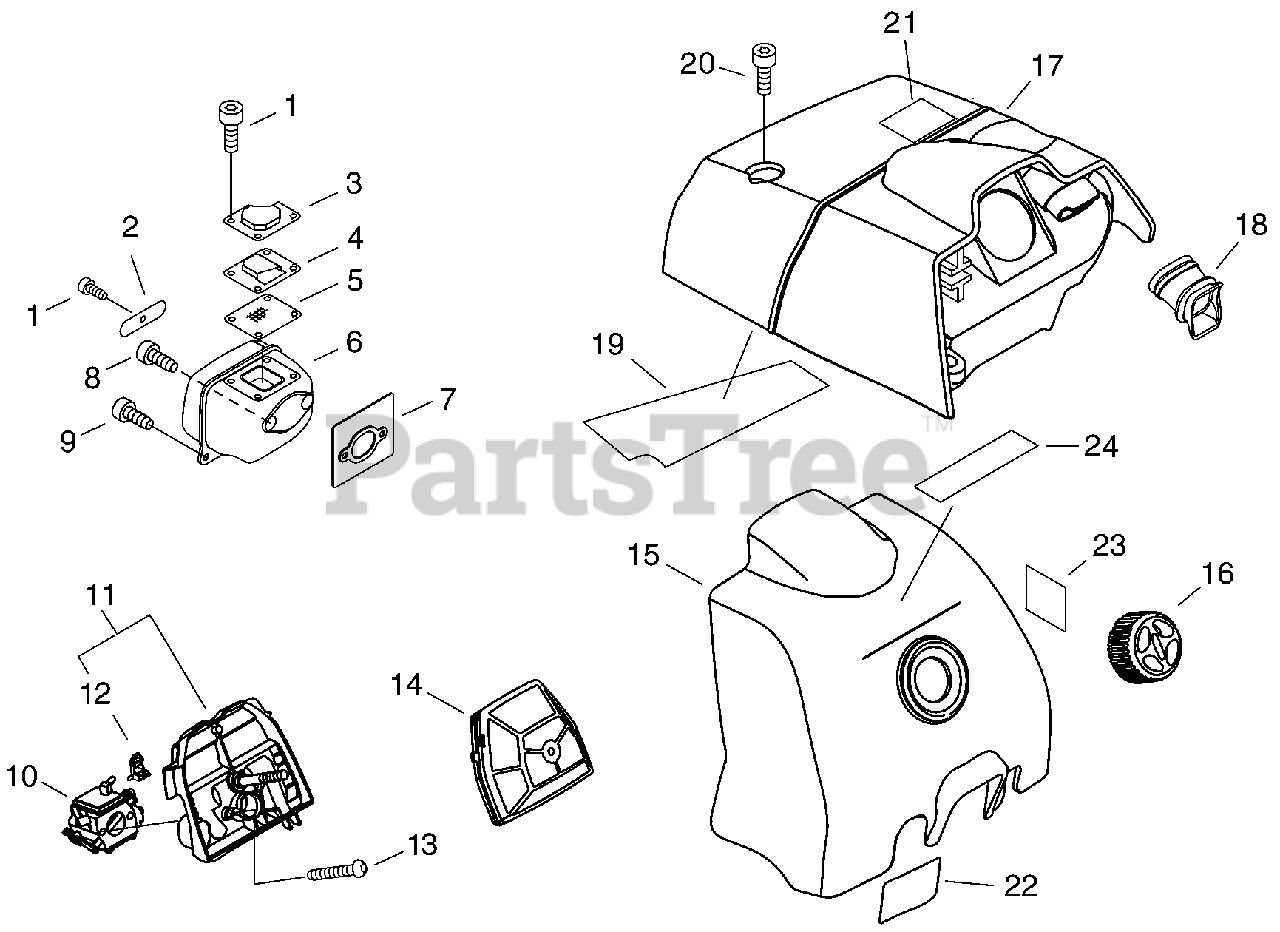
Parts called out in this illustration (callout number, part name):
1	BOLT, TORX 4×8
2	PLATE, MUFFLER
3	GUIDE, EXHAUST
4	GUIDE, EXHAUST
5	SCREEN, SPARK ARRESTER
6	MUFFLER
7	GASKET, EXHAUST
8	BOLT, TORX 5×20
9	BOLT, TORX 5×20
10	CARBURETOR - HDA-274
11	CASE ASSY, AIR FILTER
12	SHUTTER, AIR
13	BOLT, TORX 5×50
14	FILTER ASSY, AIR
15	COVER, AIR FILTER
16	KNOB, AIR FILTER COVER
17	COVER, ENGINE
18	PIPE, INTAKE
19	SHIELD, HEAT 75×32×0.15
20	BOLT, TORX 5×16
21	LABEL, CAUTION
22	LABEL, STOP
23	LABEL, CAUTION
24	LABEL, CS-600
